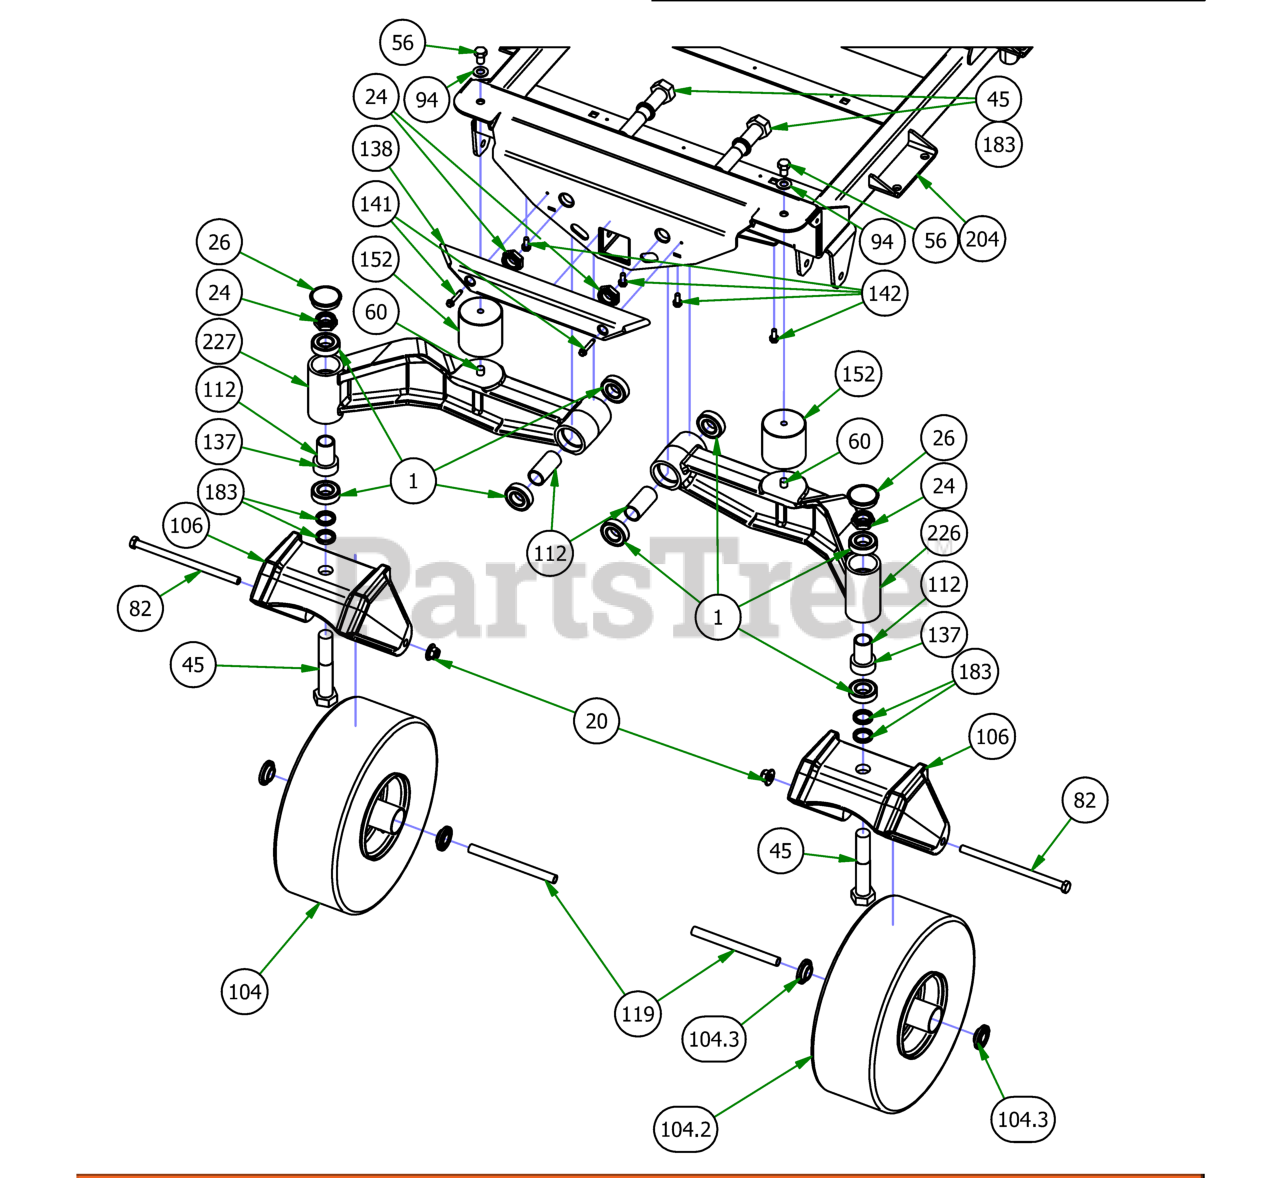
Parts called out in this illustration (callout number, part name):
1	1641 BEARING W/2 CONTACT RUBBER SEALS
20	1/2-13 NYLON INSERT FLANGE LOCKNUT ZINC
24	1" Fine Thread 1/2 Nylock Nut
26	2017 Bearing Cover
45	1-14 x 5.5 Hex Bolt Grade 8 Zinc Yellow
56	1/2" x 3/4" Hex Bolt
60	1/2-13 x 1" Stud
82	1/2" x 9" GR 5 Hex Bolt
94	1/2" Washer (Grade 8)
104	2019 15x6.00-6 Non Pneumatic Black Front Assembly
104.2	15x600-6 Tire Only
104.3	1-3/4" Bearing-Large Bore Front Rim
106	2020 R Series Cast Front Fork
112	2016 Front Bearing Spacer
119	Front Wheel Spanner
137	Rubber Stabilizer (Front Forks) [R series]
138	2017 XP Bumper
141	1/4" x 1 1/2" Self Tapping Screw
142	5/16 x 3/4 washer head type F screw
152	Vibration Mount-Blue Dot
183	Spacer, 1x1.375x.25
204	2019 Renegade Gas Frame - Powdercoated
226	2019 Front I-Beam Left
227	2019 Front I-Beam Right
